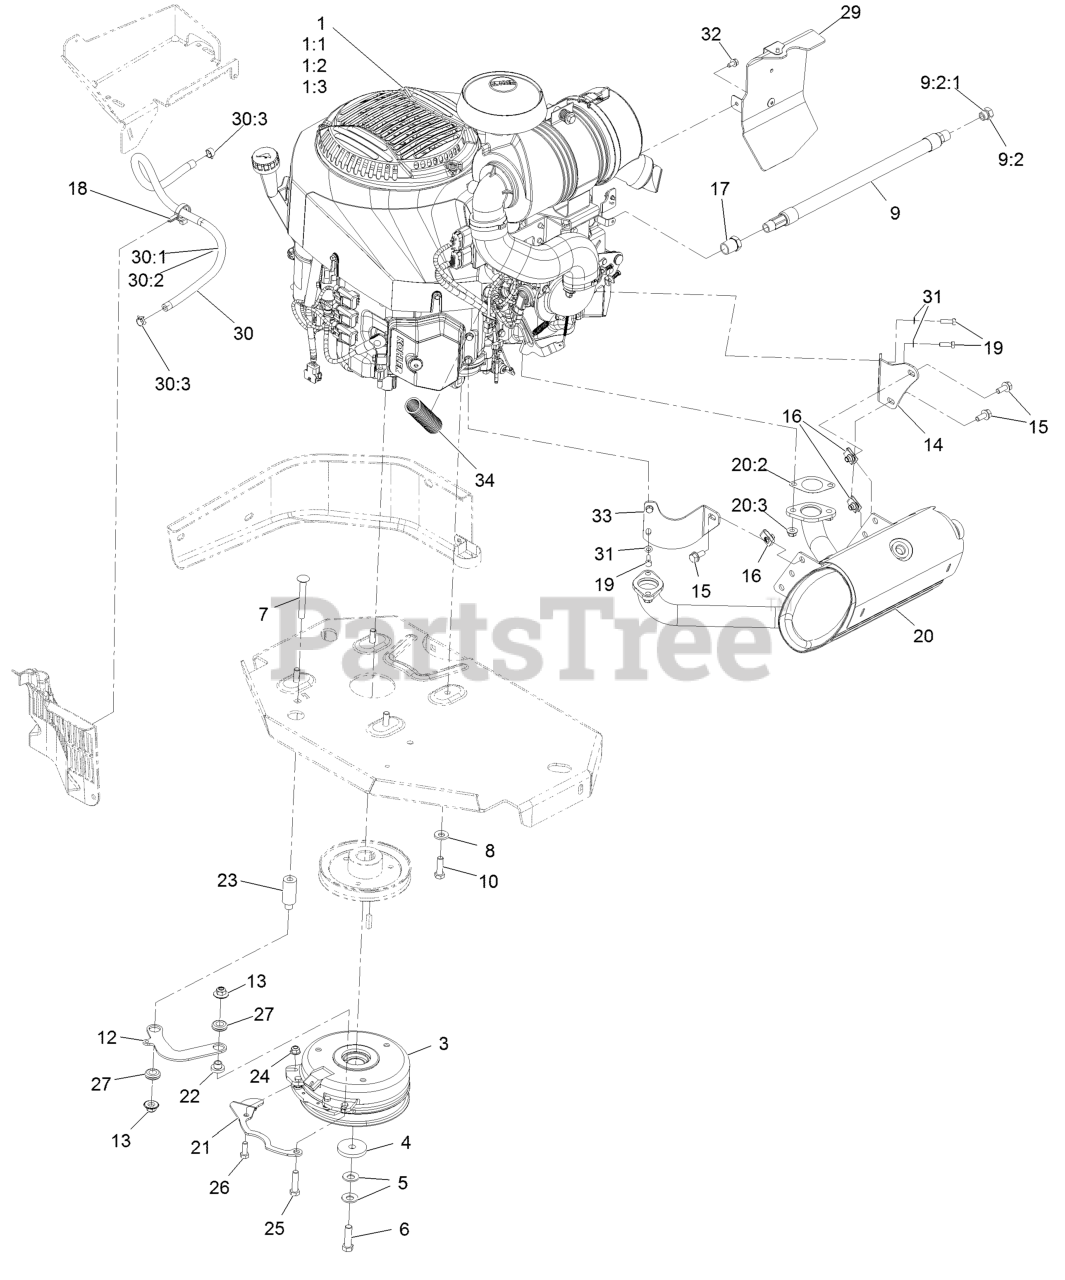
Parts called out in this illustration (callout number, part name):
1:1	Kohler 52 050 02-S Engine Oil Filter
1:2	Kohler 25 083 01-S Engine Air Filter
1:3	Kohler 25 083 04-S Safety Filter
3	CLUTCH KIT
4	WASHER-CLUTCH
5	WASHER-SPRING
6	SCREW-HH 7/16-20 X 1 1/2 W/LOCTITE
7	SCREW-CARR
8	WASHER-BELLEVILLE
9	OIL DRAIN HOSE ASM
9:2	PLUG-HH
9:2:1	O-RING
10	SCREW-HH
12	LINK-ANCHOR, CLUTCH
13	Nut-Nyloc 3/8-16 Flg
14	BRACKET-MUFFLER
15	SCREW-HHF
17	BUSHING
18	CLAMP-HOSE
19	SCREW-HH M6-1 X 20Mm W/Patch
20	MUFFLER-940-980 KOH EFI
20	MUFFLER KIT
20:2	GASKET-EXHAUST
20:3	NUT-FLANGE, LOCK
21	BELT-GUIDE
24	NUT-HF, NI
25	SCREW-HH
26	SCREW-HH
27	GROMMET-RUBBER
29	REAR BAFFLE ASM
30	FUEL LINE ASM
30:1	HOSE-FUEL
30:2	SLEEVE, THERMAL
30:3	CLAMP-HOSE
31	WASHER-SPRING
32	SCREW-HWH
33	BRACKET-MUFFLER, FRONT
34	CONDUIT-CONVOLUTED
